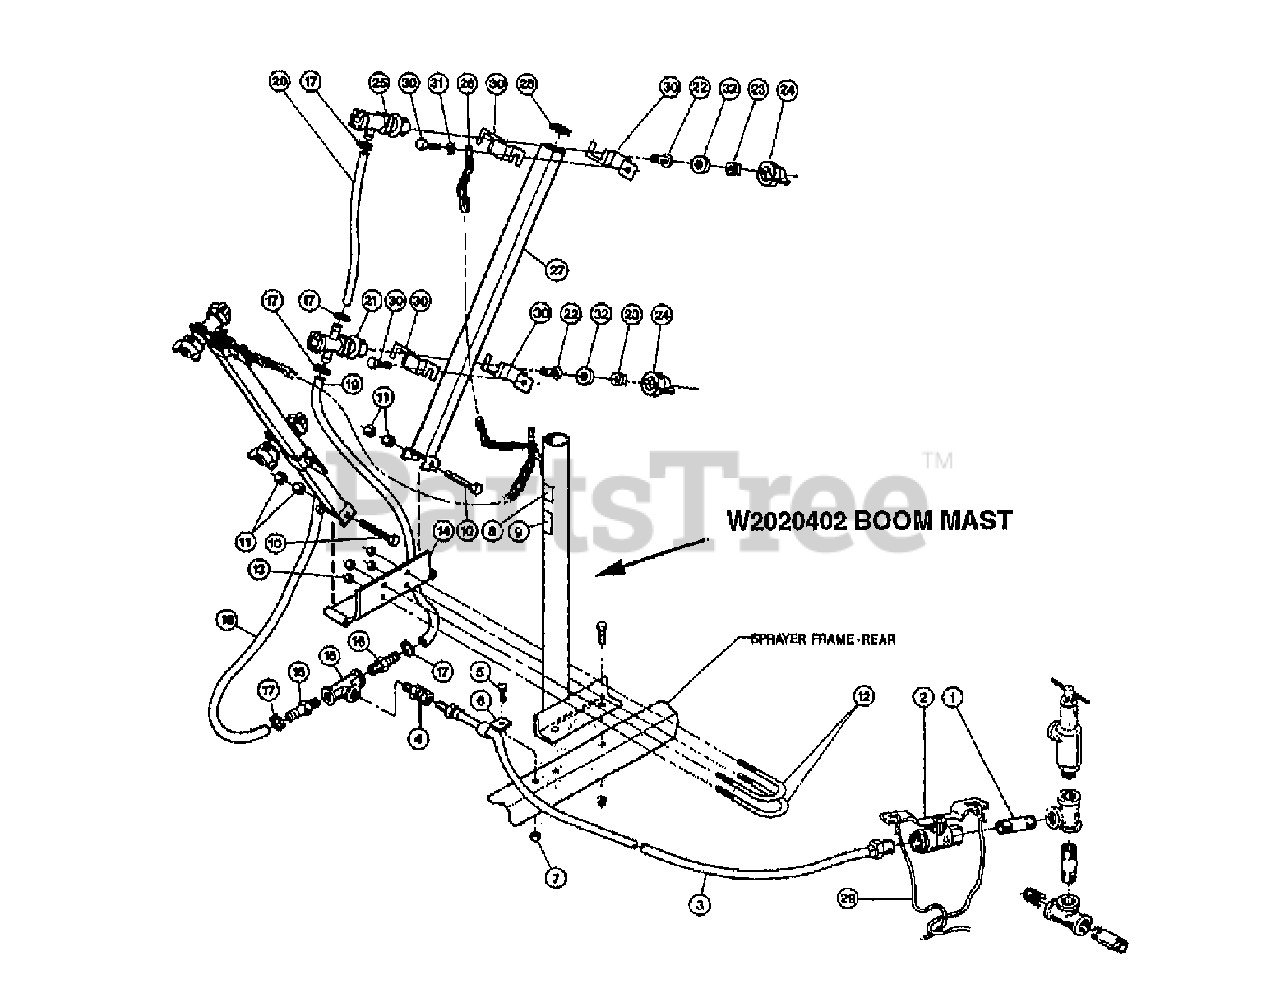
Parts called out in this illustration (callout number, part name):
1	NIPPLE-PIPE 50X2 GALVANIZED
2	VALVE-BALL .5 WING HANDLE
3	ASSM-44" HOSE W/CLAMPS W207566
4	ADAPTER-.25FPT X .25NPT
5	SCR-SLOT.H.10-24X2
6	CLAMP-HOSE NYLON
7	SCR-PHS M10-24X.75 ZP
8	DECAL-DANGER AVOID W2045146
9	DECAL-40PSI CAUTION W2045147
10	OBS SCR HH 5/16-18X2.5
11	NUT-HEX 5/16-18 ZP
12	BOLT-U .25 X 1.75 X 3
13	NUT-HEX 1/4-20 ZP
14	ASSM-BOOM SWVL PLATE
15	TEE-PIPE .25FPT BRASS
16	SHANK-HOSE .375 X .25NPT
17	CLAMP-HOSE 10829
18	HOSE-VINYL 7.5" 300PSI
19	HOSE-VINYL 11.5" 300PSI
20	HOSE-VINYL 18" 300PSI
21	NOZZLE BODY W/2HOSE SHANK
22	STRAINER-NYLON W8079PP
23	NOZZLE-BRASS SPRAY BOOM
24	CAP-NOZZLE (BOOM ATTCH)
25	NOZZLE BODY SINGLE SHANK
26	CHAIN-DOUBLE LOOP W2020104B
27	ASSM-BOOM TUBE
28	PLG-SQ 16GA TUBE OLD W9565K23
29	ROPE-.25 X 10'
30	ASSM-CLAMP & SCR
31	WASHER-.75X.312X.065 ZP
32	GASKET-NOZZLE SEAT
